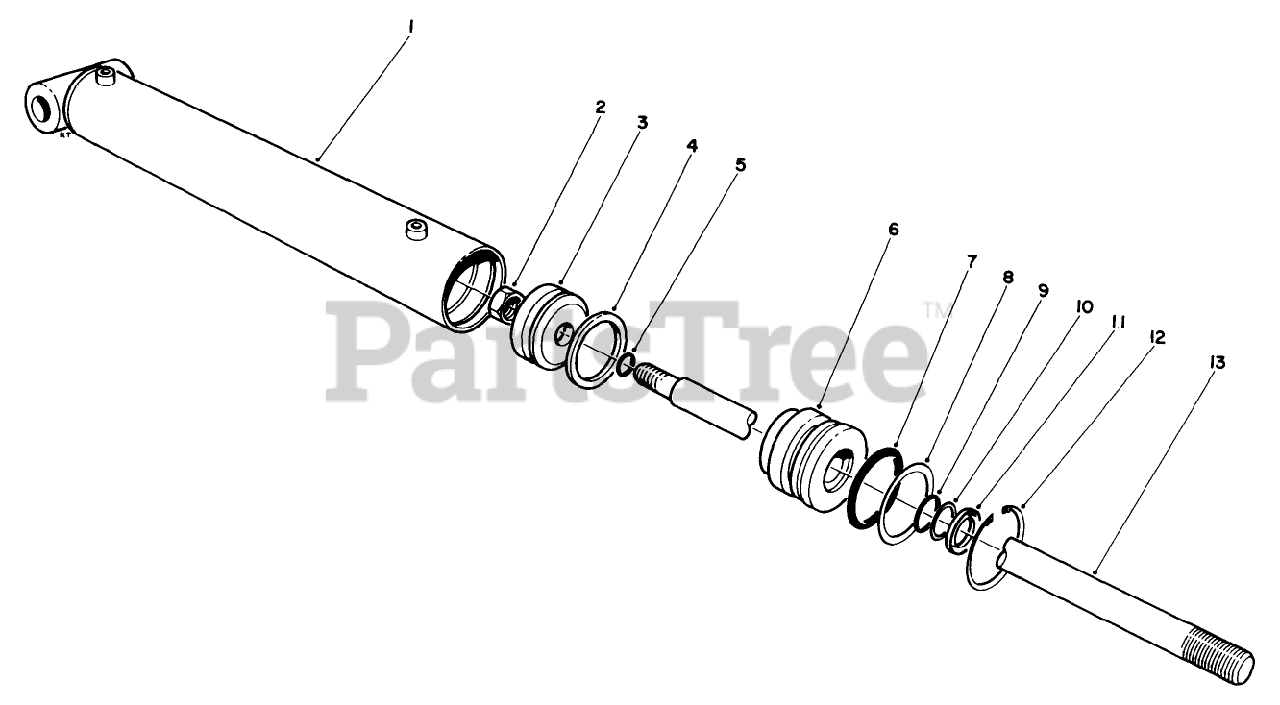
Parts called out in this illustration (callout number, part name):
1	Barrel
2	LOCKNUT
3	PISTON
5	O Ring
7	O Ring
9	O Ring
11	Dust Seal
12	RING-RETAINING
13	SHAFT
